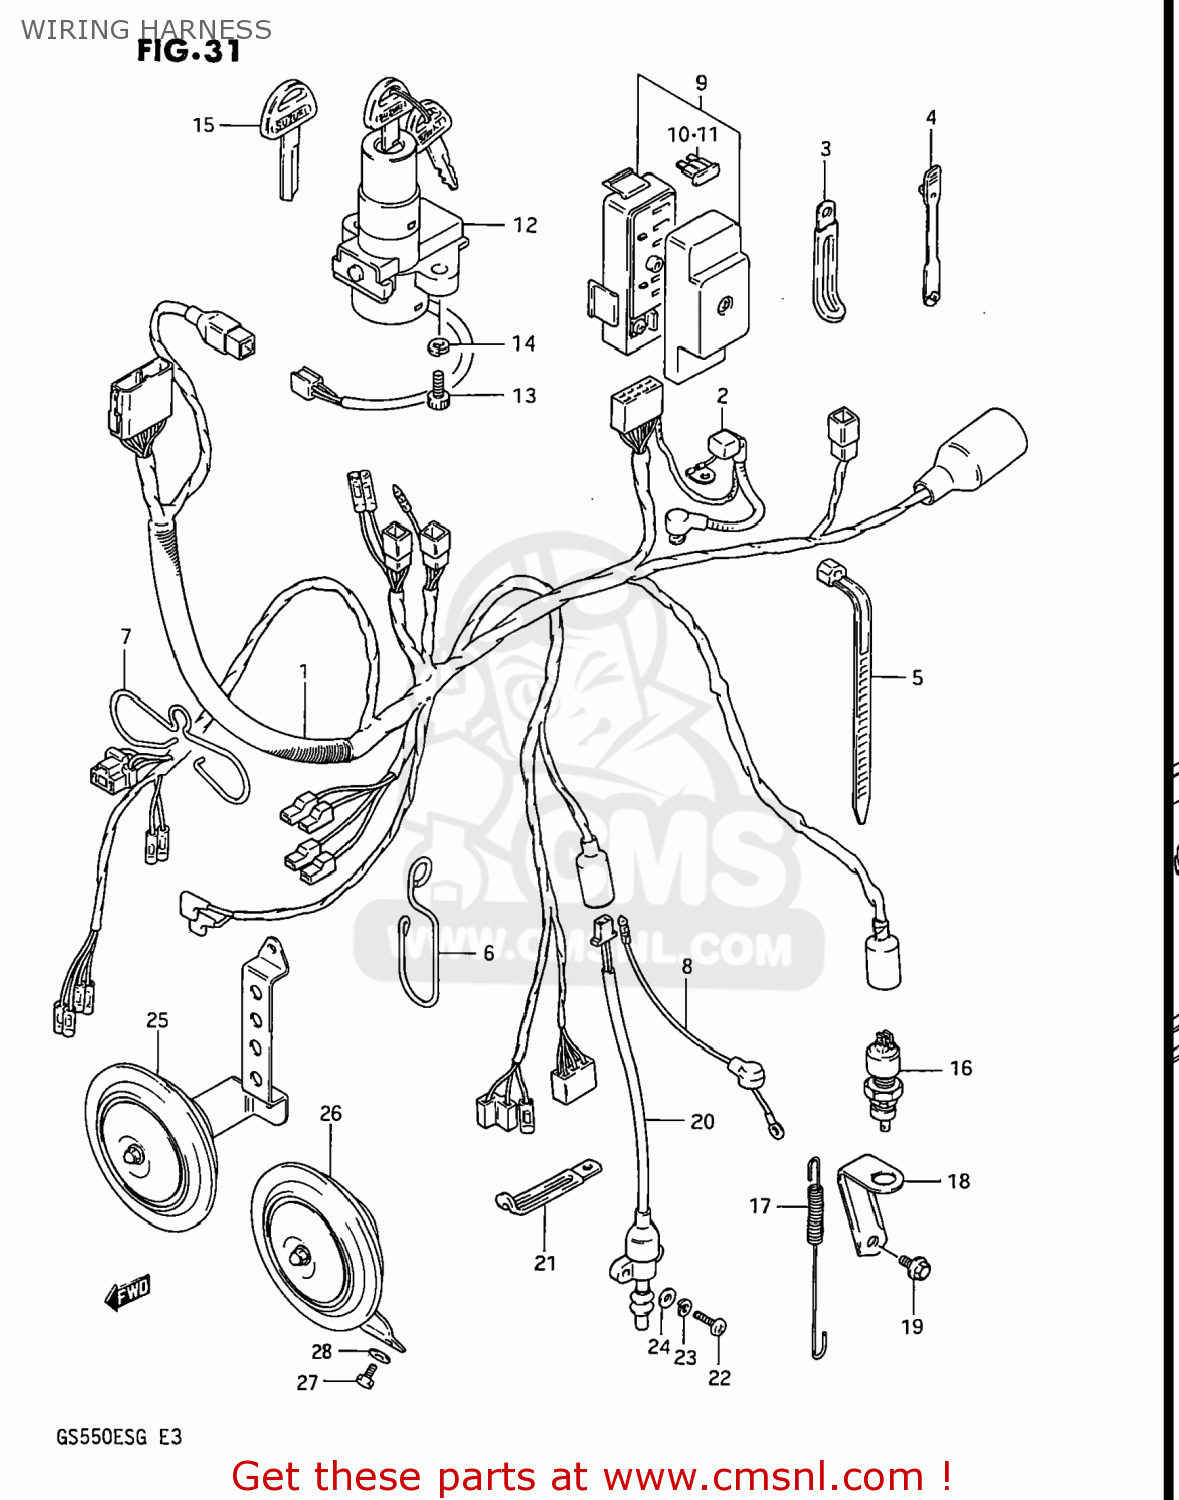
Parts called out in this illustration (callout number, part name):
1	HARNESS,WIRING
2	CAP,BATTERY PLUS TERMINAL
3	CLAMP
4	CLAMP,L:88
5	CLAMP(L:95)
6	GUIDE,WIRING HARNESS
7	BOOT,WIRING HARNESS
8	WIRE
9	FUSE BOX ASSY
10	FUSE(10A)
11	FUSE(15A)
12	IGNITION SWITCH/STEERING LOCK
13	BOLT
14	WASHER,LOCK
15	KEY,BLANK
16	SWITCH ASSEMBLY,STOP LAMP
17	SPRING
18	BRACKET,BRAKE LAMP SWITCH
19	BOLT
20	SWITCH ASSEMBLY,SIDE STAND
21	CLAMP
22	SCREW 5X20
23	WASHER,LOCK
24	WASHER,5MM
25	HORN ASSEMBLY
26	HORN ASSEMBLY
27	BOLT
28	WASHER,LOCK
